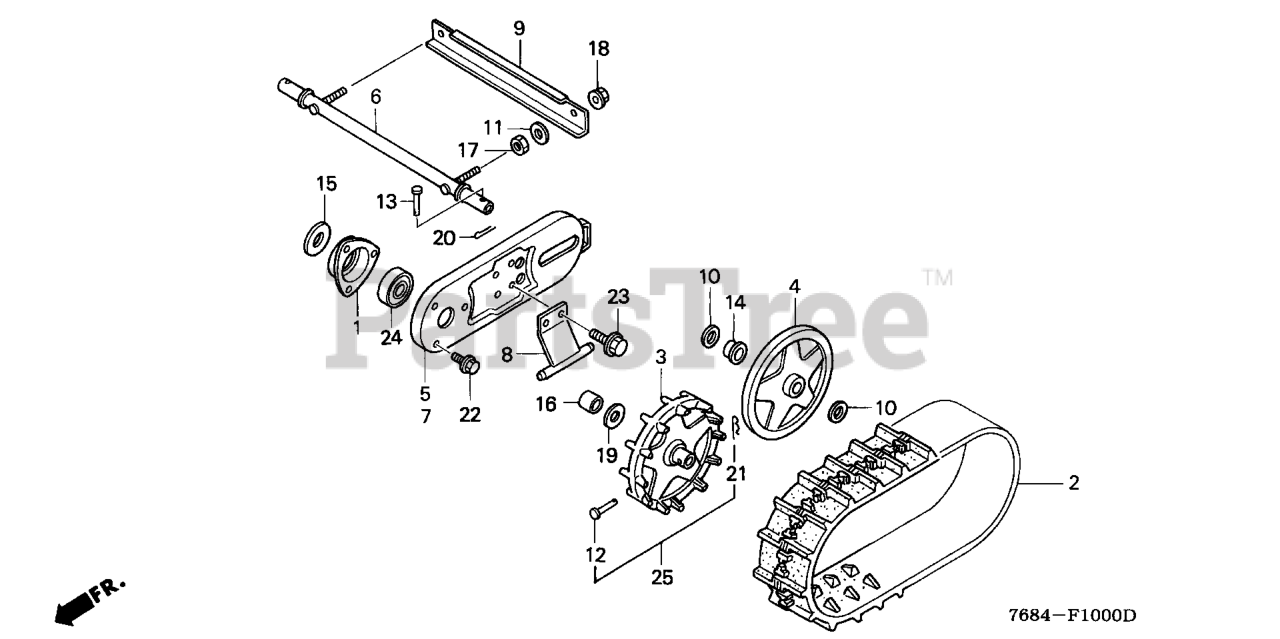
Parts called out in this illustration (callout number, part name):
1	HOLDER, WHEEL SHAFT BEARING
2	CRAWLER (12-60X21)
3	SPROCKET, CRAWLER
4	ROLLER, CRAWLER
5	PLATE, R. CRAWLER
6	PIPE, CRAWLER
7	PLATE, L. CRAWLER
8	GUIDE, CRAWLER
9	BAR, CRAWLER PLATE
10	WASHER, PLAIN (22MM)
11	WASHER, PLAIN (10MM)
12	PIN (6.2X38)
14	COLLAR, CRAWLER PIPE
15	COLLAR, R. WHEEL SHAFT
16	COLLAR, CRAWLER SPROCKET
17	NUT, FLANGE (10MM)
18	NUT, FLANGE (10MM)
19	WASHER, PLAIN (20MM)
20	PIN, COTTER (3.0X18)
21	PIN, COTTER (3.0X18)
22	BOLT, FLANGE (6X12) Use up to Engine SN 1543277.
23	BOLT, FLANGE (8X14)
24	BEARING, RADIAL BALL (6004UU)
25	PIN SET, CRAWLER
